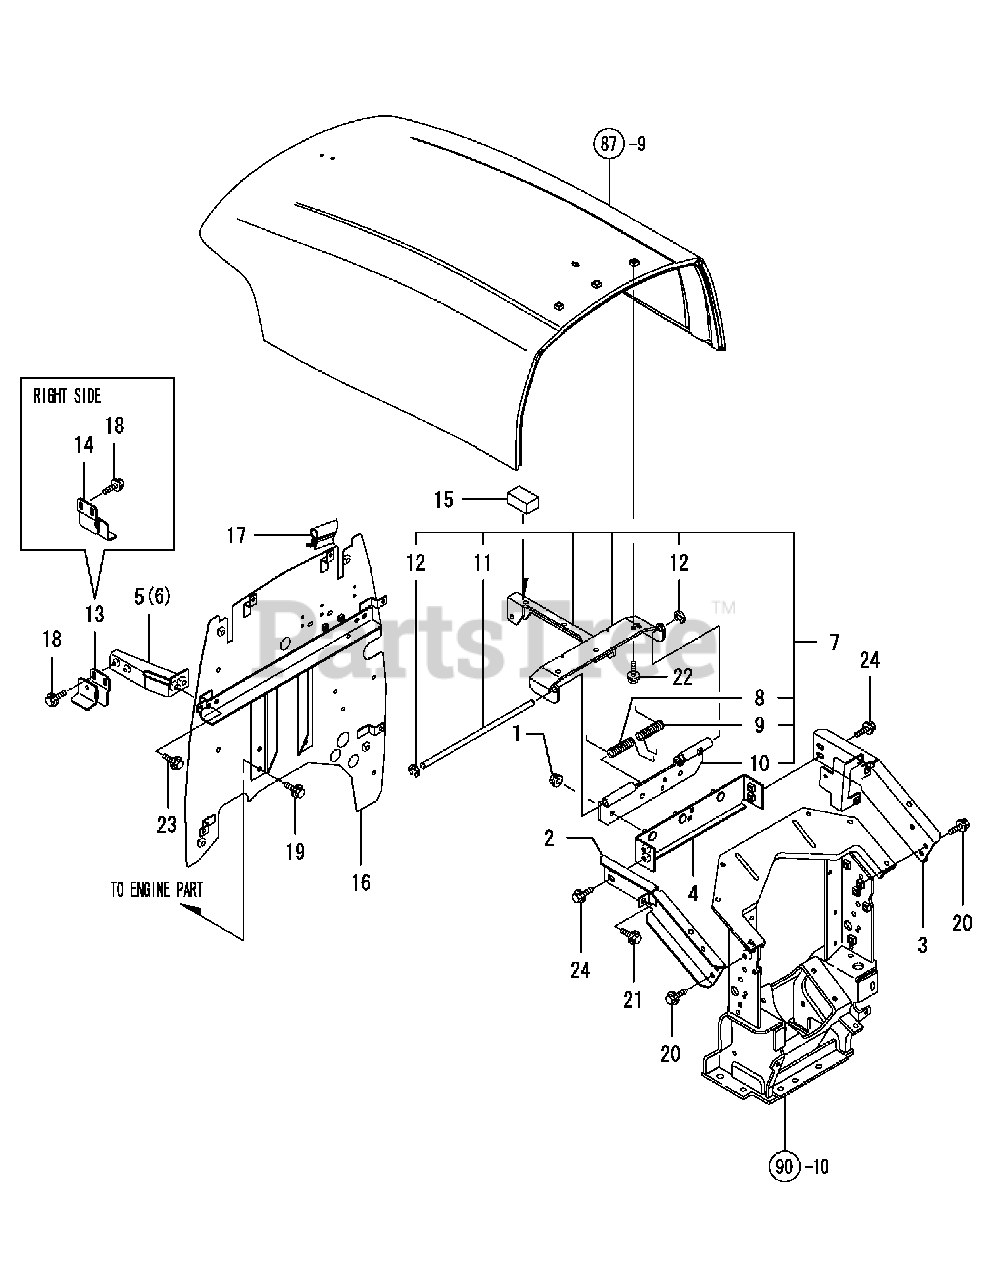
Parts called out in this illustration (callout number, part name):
1	NUT W/WASHER 8
2	FRAME ASSY,SIDE L.H.
3	FRAME ASSY,SIDE R.H.
4	PLATE ASSY,UPPER
5	SUPPORT, L.H. COVER
6	SUPPORT, R.H. COVER
7	HINGE ASSY,HOOD
13	BRACKET, L.H. COVER
14	BRACKET, R.H. COVER
16	PLATE ASSY,SHIELD
17	STRIP,DUCT WEATHER
18	BOLT M 6X 12 PLATED
19	BOLT M 8X 12 PLATED
20	BOLT M 8X 16 PLATED
21	BOLT M 8X 16 PLATED
22	BOLT M 8X 16 PLATED
23	BOLT M 8X 16 PLATED
24	BOLT M 8X 16 PLATED
